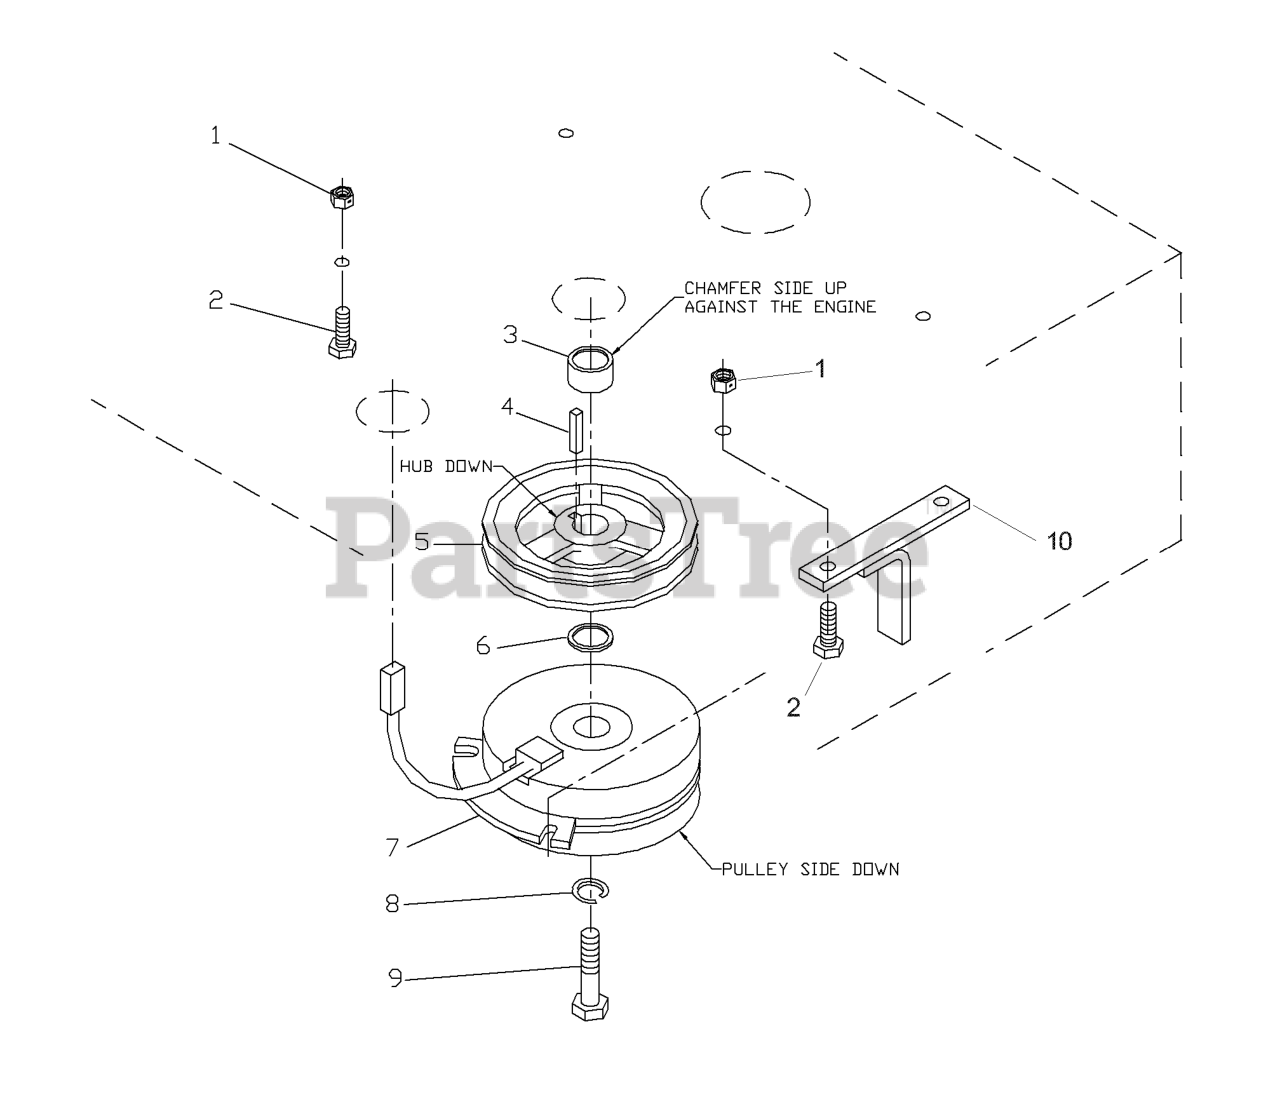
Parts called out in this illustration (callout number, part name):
1	NUT 5/16C CENTERLOCK
2	HCS 5/16C X 1 3/4
4	KEY 1/4 SQ X 1 1/8
6	BUSHING, 10GA MACHINERY
7	CLUTCH, ELECTRIC
8	WASHER 7/16 LOCK
9	BOLT 7/16F X 2 1/2
10	CLUTCH TIE DOWN
